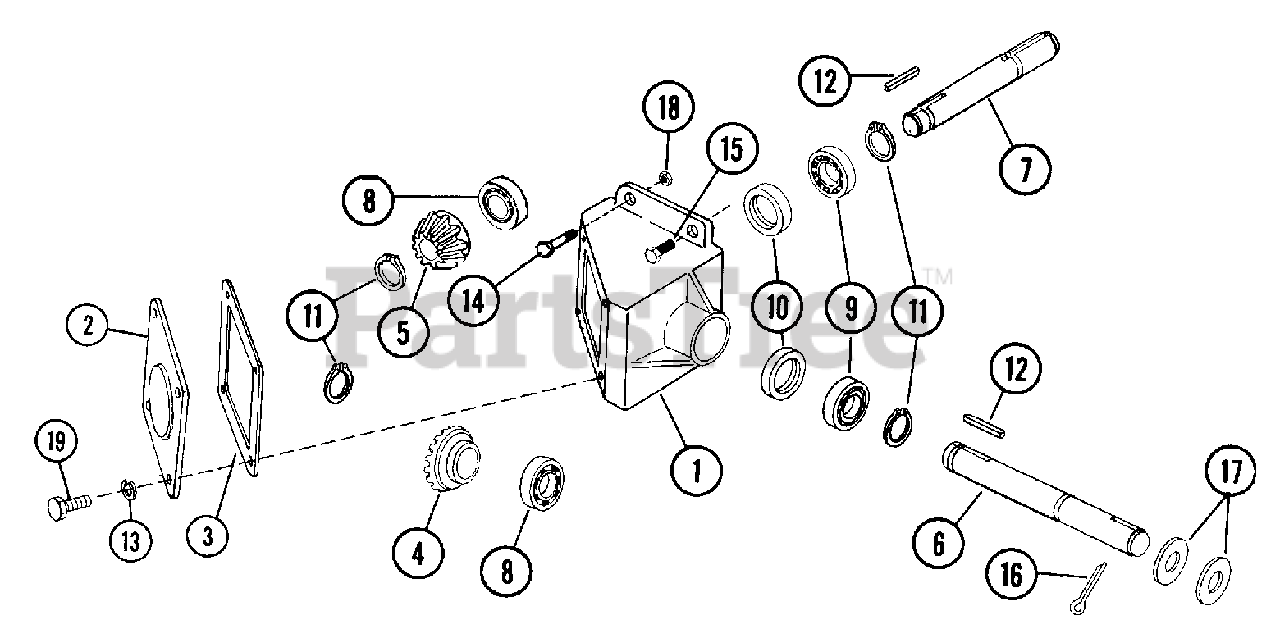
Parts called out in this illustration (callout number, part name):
1	GEARBOX HOUSING
2	GEAR BOX LID
4	OUTPUT GEAR
5	INPUT GEAR
6	OUTPUT SHAFT
7	INPUT SHAFT
8	BRG-BALL .750X1.625X.31
9	BRG-BALL .750X1.625X.50
10	SEAL .750X1.624X.312
11	RG-RTNG-EXT .750X.042
12	KEY-SQ .188X.68X.188 DANUSER
13	WSHR-LK .250X.077 HVY PL
14	BLT-HEX .38-16X1.75 PL GR2
15	BLT-HEX .38-16X1.25 PL GR5
16	PIN-COTR .12 X 1.25 PL
17	WSHR-FL-STL .781X1.250X.059 PL
18	NUT-LK-CTR .375-16 GR A PL
19	BLT-HEX .25-20X.50 PL GR2
